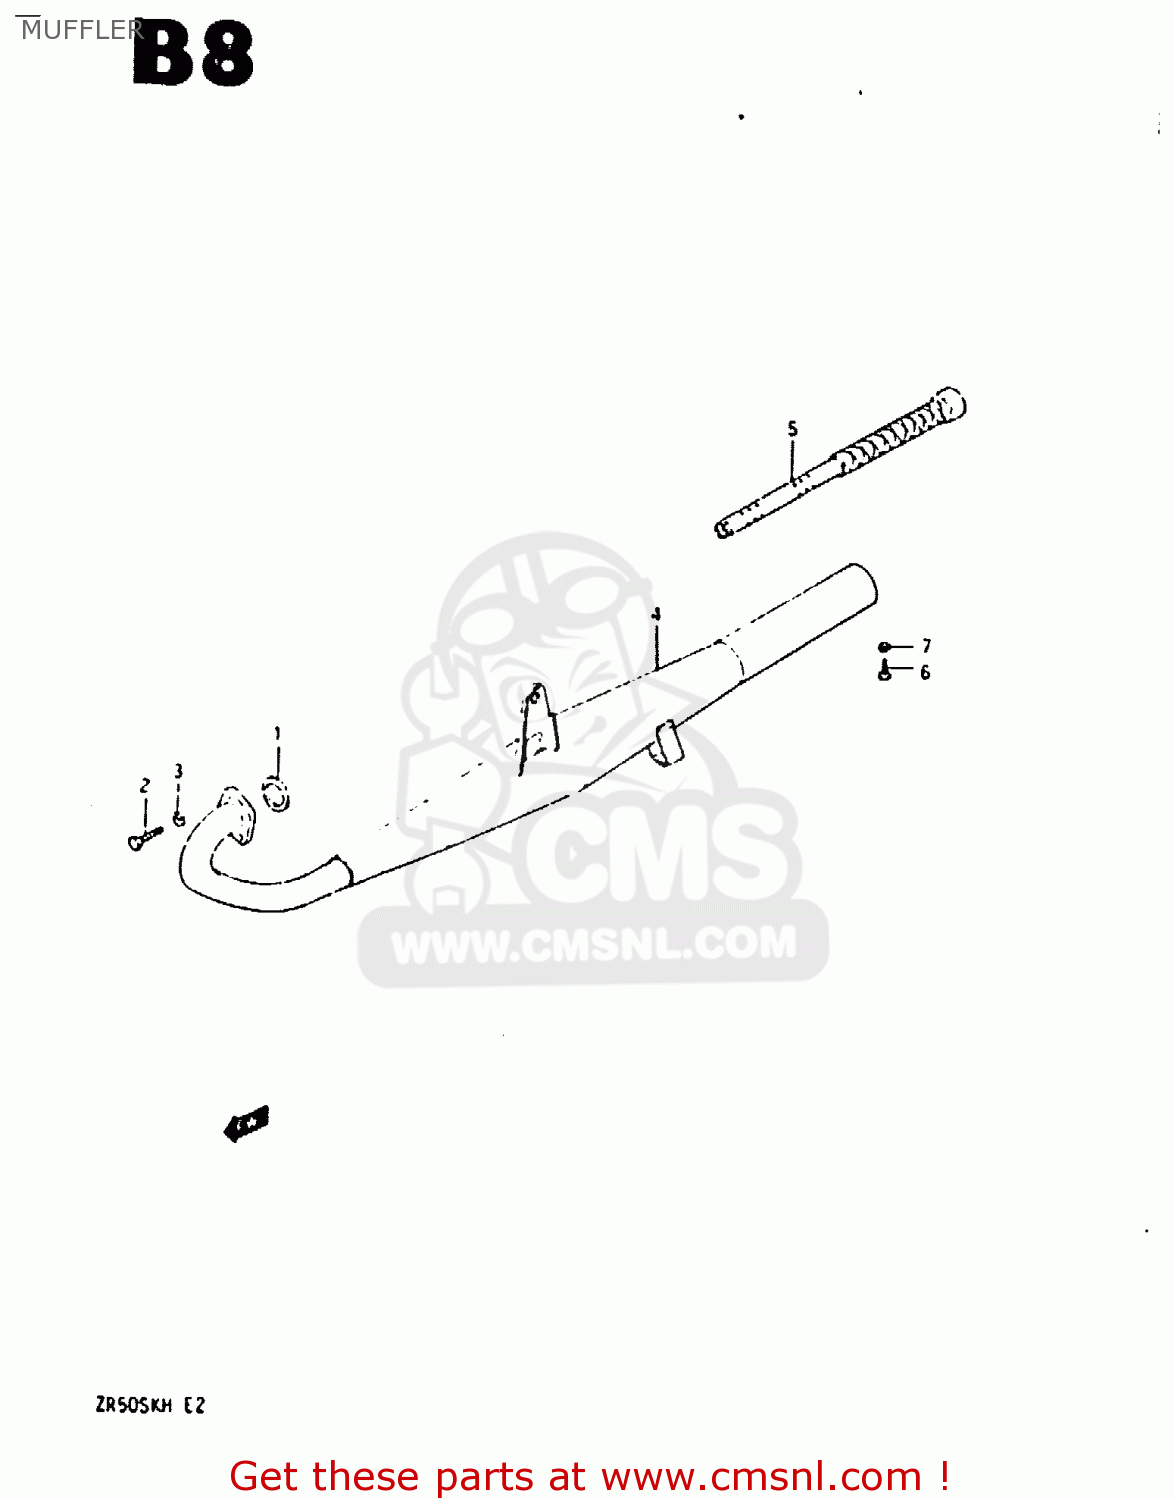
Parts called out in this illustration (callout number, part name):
1	GASKET,EXHAUST PIPE (NAS)
2	BOLT
3	WASHER,LOCK
4	MUFFLER ASSY
5	PIPE, BAFFLE
6	BOLT(5X8)
7	LOCK WASHER
